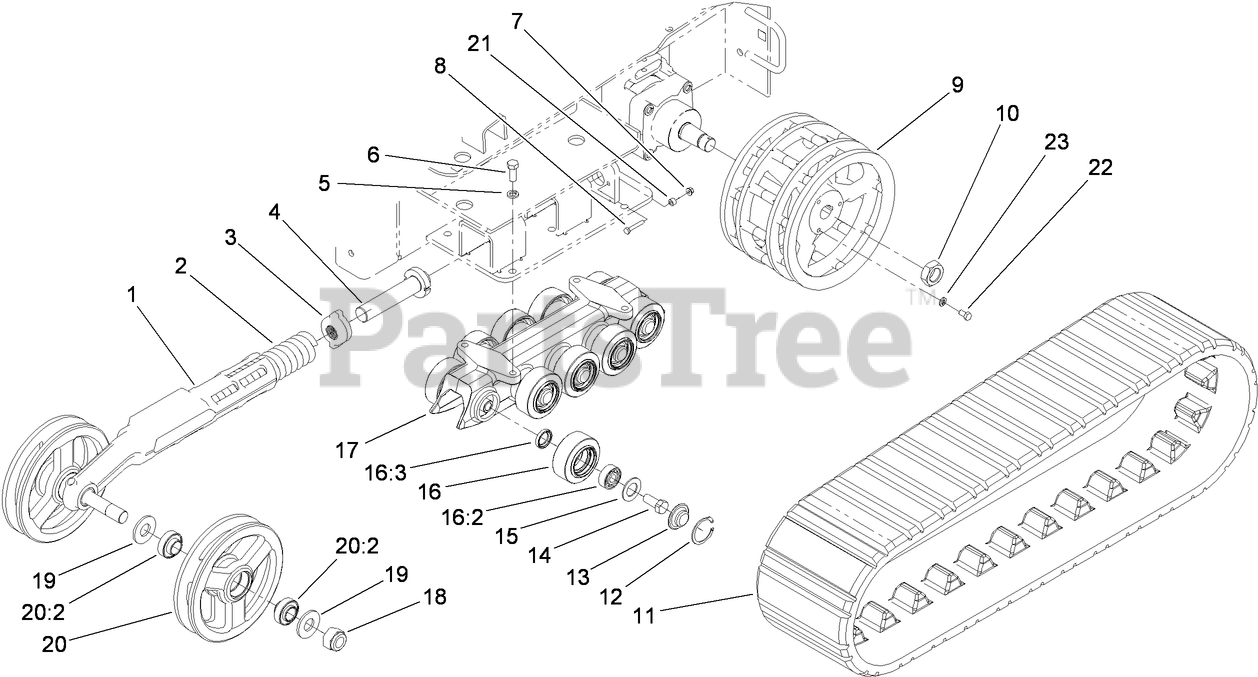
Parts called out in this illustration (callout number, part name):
1	ARM-TENSIONER
2	SPRING-COMPRESSION
3	BLOCK-TENSIONER
4	BOLT-TENSIONER
5	WASHER-LOCK
6	SCREW-HH
7	NUT-HHF
8	SCREW-HH
9	WHEEL-DRIVE
10	NUT-HEX
11	TRACK
12	RING-SNAP, INTERNAL
13	CAP-WHEEL, BEARING
14	SCREW-HH
15	Gasket-Bogie
16	Road Wheel ASM
16:2	BEARING
16:3	SEAL-OIL
17	GUIDE-TRACK
18	NUT-HEX, NI
19	WASHER-PLAIN
20	Tensioner Wheel ASM
20:2	Bearing-Ball
21	SPACER
22	SCREW-HH
23	WASHER-LOCK
